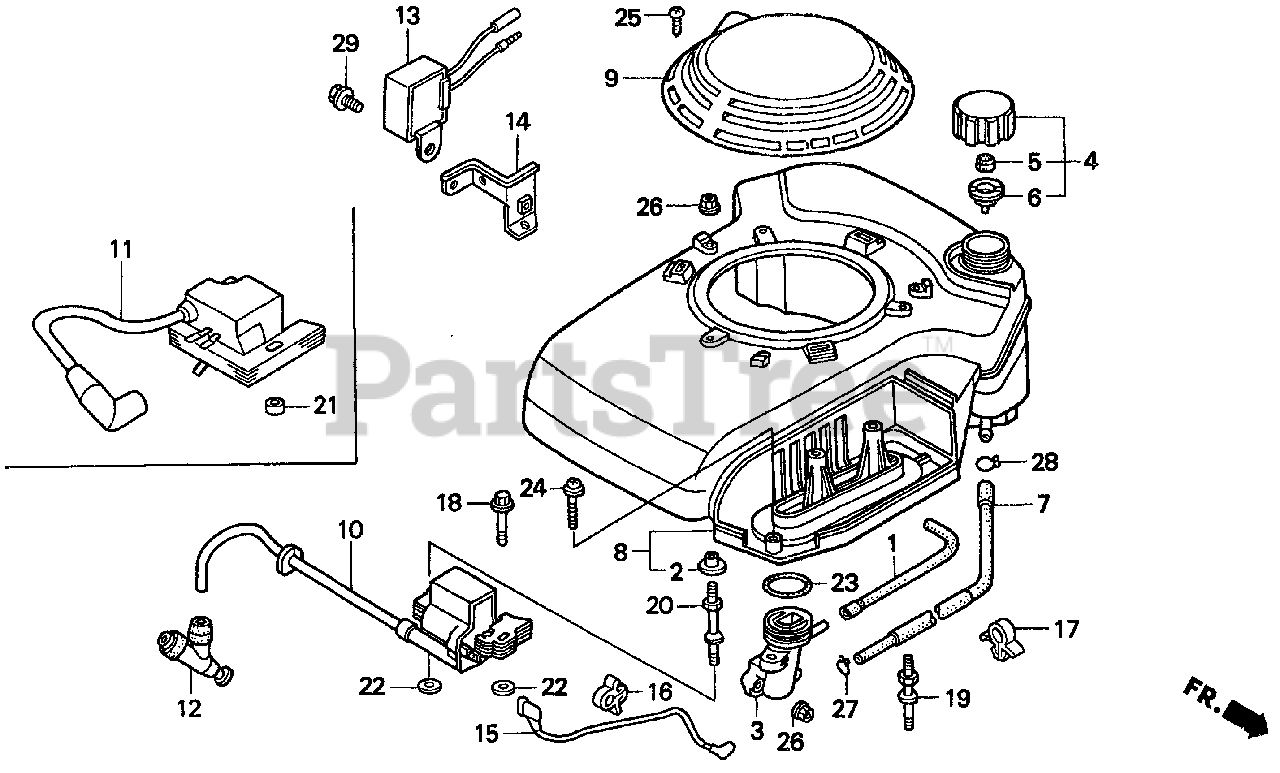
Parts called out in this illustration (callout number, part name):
1	TUBE, BREATHER
2	COLLAR, AIR CLEANER
3	ELBOW, AIR CLEANER
4	CAP ASSY., FUEL TANK
5	SPONGE, FUEL CAP BREATHER
6	GASKET, FUEL CAP
7	TUBE ASSY., FUEL TANK
8	COVER, FAN *NH1* (BLACK)
8	COVER, FAN *R8* (TEXTURED) (BRIGHT RED)
9	HOOD, FAN COVER *NH1* (TEXTURED) (BLACK)
9	HOOD, FAN COVER *R8* (TEXTURED) (BRIGHT RED)
9	HOOD, FAN COVER *R8* (BRIGHT RED)
10	COIL ASSY., IGNITION
12	CAP ASSY., NOISE SUPPRESSOR
13	RECTIFIER, SILICON
14	STAY, RECTIFIER
15	WIRE, STOP SWITCH
16	HOLDER, STOP SWITCH WIRE
17	CLAMP, BRAKE PIPE
18	BOLT, FLANGE (6X28)
19	BOLT A, STUD
20	BOLT, STUD (IGN COIL)
22	WASHER, PLAIN (6MM)
23	O-RING (33.3X3.5)
24	SCREW-WASHER (6X35)
25	SCREW, TAPPING (4X20)
26	NUT, FLANGE (6MM)
27	CLIP, TUBE (B8)
28	CLIP, TUBE (B10)
28	CLIP, TUBE (C9)
29	BOLT, FLANGE (6X10)
